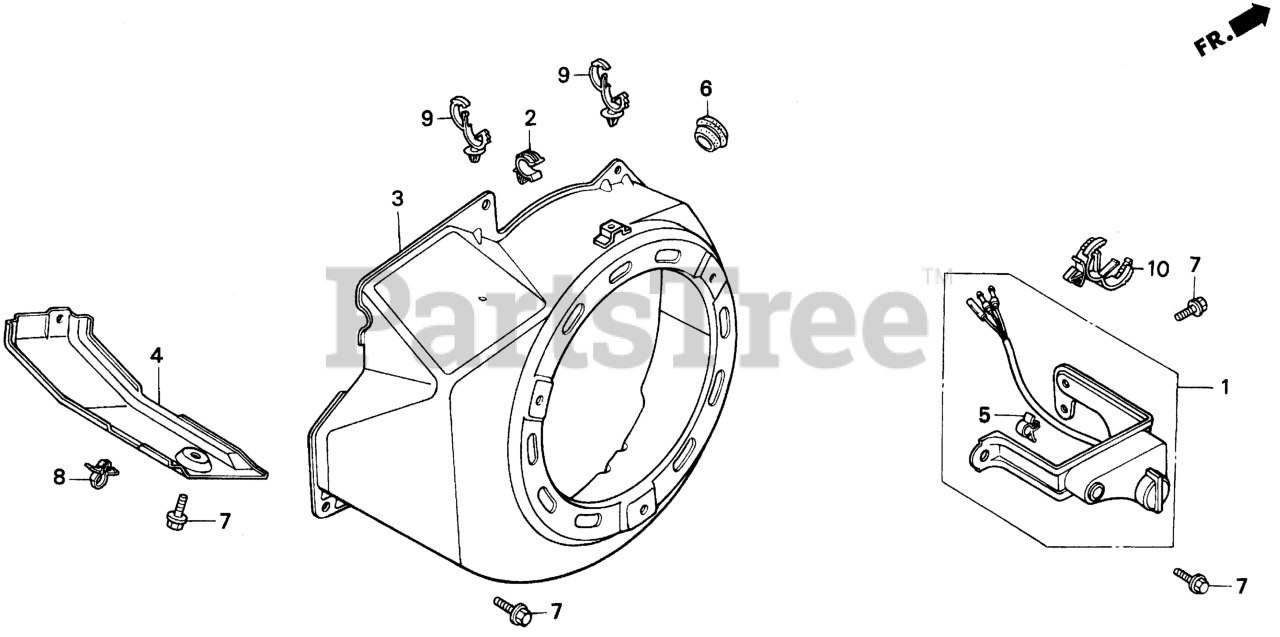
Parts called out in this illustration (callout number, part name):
3	COVER, FAN *R280* (POWER RED)
4	SHROUD
6	GROMMET, DRAIN HOLE
7	BOLT, FLANGE (6X12) (CT200)
9	CLIP, WIRE HARNESS (6MM) (WHITE)
